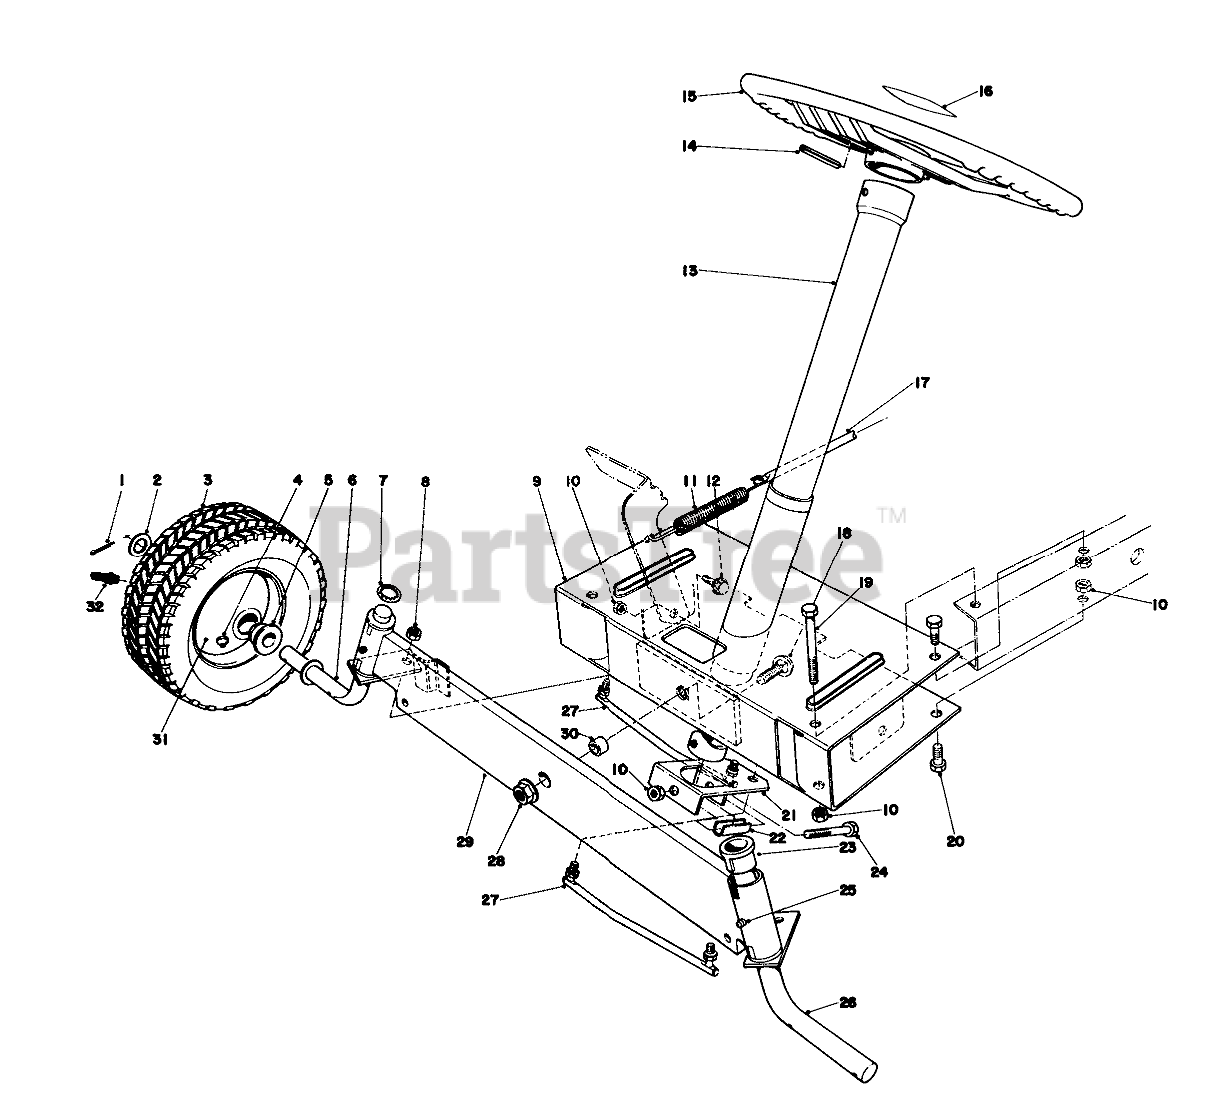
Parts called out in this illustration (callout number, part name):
1	PIN-COTTER
2	WASHER-FLAT
3	Tire Turf King
4	FITTING-GREASE
5	BUSHING
6	SPINDLE WA RH
7	Retaining Ring
8	NUT-LOCK NI
9	Front Frame
10	NUT-LOCK, CONE
11	Brake Spring
12	SCREW-SHOULDER
13	Steering Tube
14	PIN-ROLL
15	Steering Wheel
16	Decal
17	Brake Rod
18	SCREW-CARR
19	SCREW-HH
20	SCREW-HH
21	Lever Steering
22	Spacer-Steering Tube
23	BUSHING
24	SCREW-HH
25	Fitting-Grease
26	Spindle L.H.
27	TIE ROD ASM
28	NUT-HF
29	Front Axle
30	FRONT AXLE SPACER
32	STEM-VALVE
